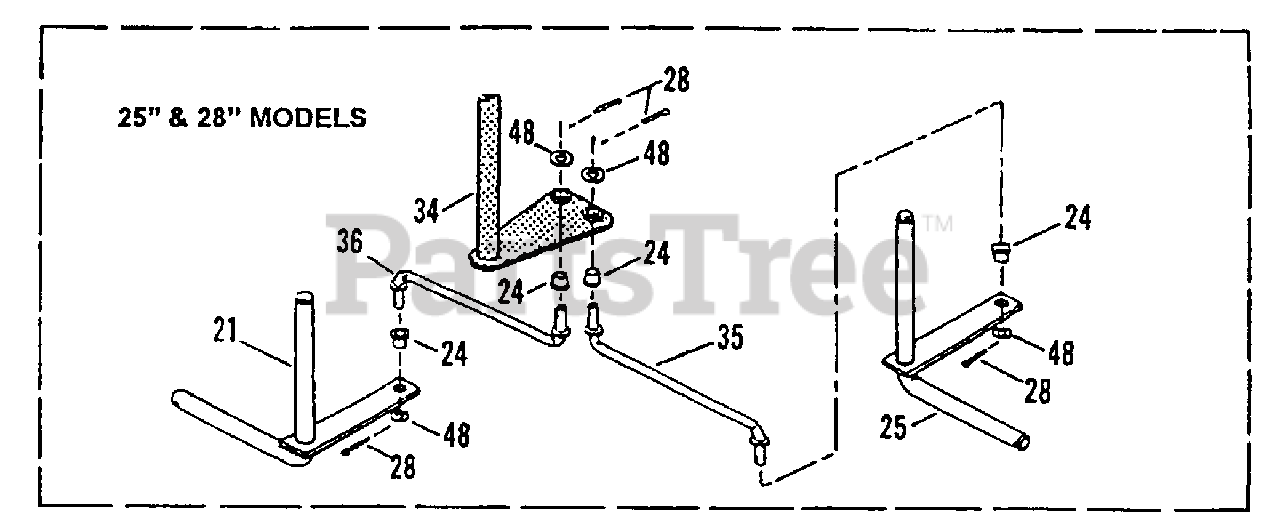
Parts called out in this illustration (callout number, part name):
21	PIN, Narrow King (Right Side)
24	BUSHING, Tie Rod
25	PIN, Narrow King (Left Side)
28	COTTER-PIN, 5/32 x 1"
34	SHAFT, Steering (Narrow Front End)
35	TIE-ROD, Left Side 7.67"
36	TIE-ROD, Right Side 7.67"
48	WASHER, 3/8" Flat
